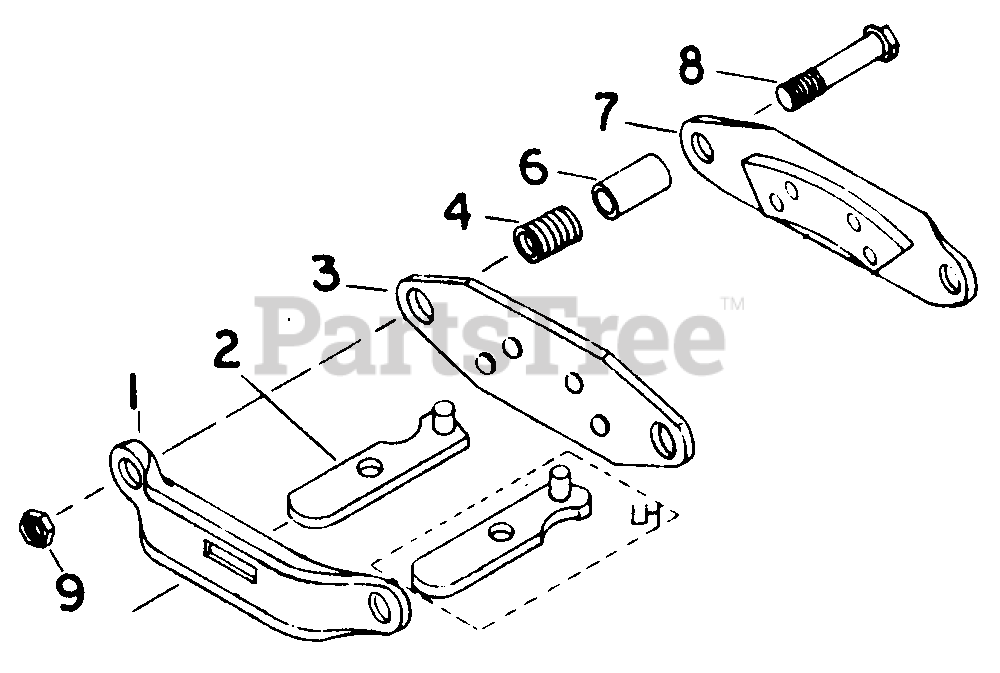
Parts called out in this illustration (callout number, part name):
1	Bracket, Cam
3	Plate, Flat Pad Holder
4	Spring, Compression
6	Bushing
7	Plate, Ribbed Pad Holder
8	Bolt, 3/8-NF X 2-1/4 Type 5
9	Nut, 3/8-NF P/T Lock Type 5
